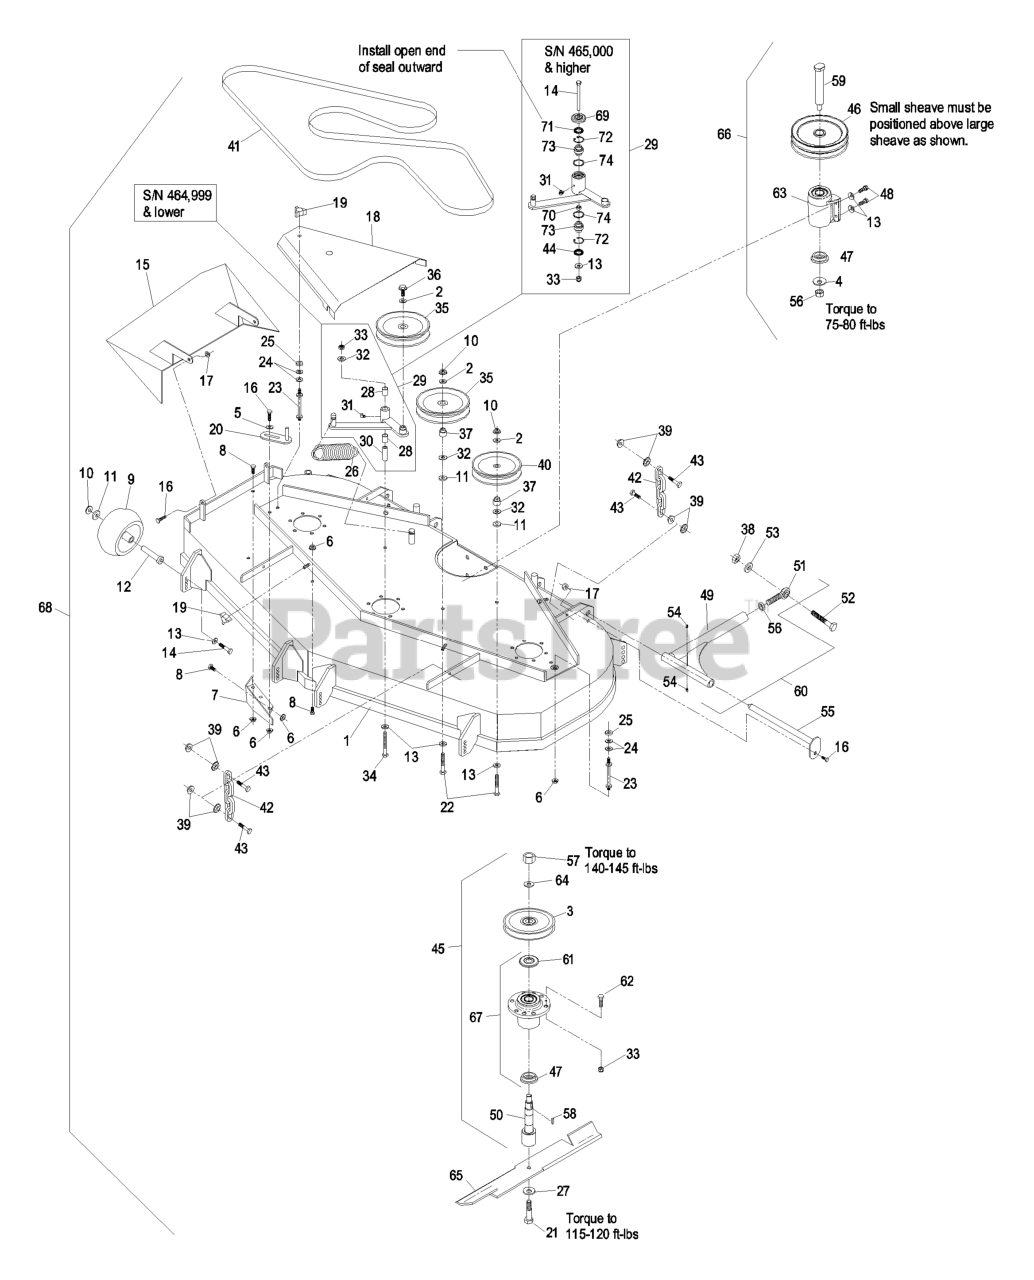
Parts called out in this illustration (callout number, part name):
1	ASM,DECK W/DECALS LZ524
2	WASHER-FLAT
3	SHEAVE,BLADE DRIVE 6.30
4	WASHER-SPRING
5	WASHER-SPRING
7	WLD,BAFFLE DISCHARGE
8	SCREW-HH
9	ROLLER-SCALP, ANTI
10	NUT-HHF, WHIZ
12	BUSHING-ROLLER
13	WASHER-BELLEVILLE
14	SCREW-HH
15	WLD,CHUTE DICHARGE 524
16	SCREW-HH
17	NUT-LOCK, NI
18	SHIELD,BELT 52
19	KNOB-3 PRONG
20	GUIDE-BELT
21	SCREW-CAP
22	SCREW-HH
23	STUD-SHIELD, BELT (SHORT)
24	WASHER-FLAT
27	WASHER-BLADE BOLT, HEAVY
28	SLEEVE-BEARING
29	KIT,DECK IDLER LZ/XP
30	BUSHING
31	FITTING-GREASE, 90 DEG
32	WASHER-FLAT
33	NUT-LOCK, NI
34	SCREW-HH
36	SCREW-HHF
37	BUSHING-IDLER
38	NUT-HEX
40	PULLEY-IDLER
41	BELT,BLADE DRIVE 52
42	CHAIN-LIFT, DECK
43	SCREW-HH
44	SEAL-LIP, DOUBLE
46	SHEAVE,JACKSHAFT - DBL
47	SPACER-GUARD, BOTTOM
48	SCREW-HH
50	SPINDLE,SHORT
51	BALLJOINT-SPHERICAL
52	SCREW-HH
53	WASHER-LOCK
54	FITTING-GREASE
55	PIN-STRUT
56	NUT-HEX
59	JACKSHAFT
60	STRUT ASM
61	GUARD-BEARING, TOP
62	SCREW-HH
66	KIT,JACKSHAFT 52-3750
68	Asm, Deck Complete
69	GUARD-TOP
70	SPACER
71	SEAL-LIP, SINGLE
72	RING-SNAP
73	BEARING-SPHERICAL
